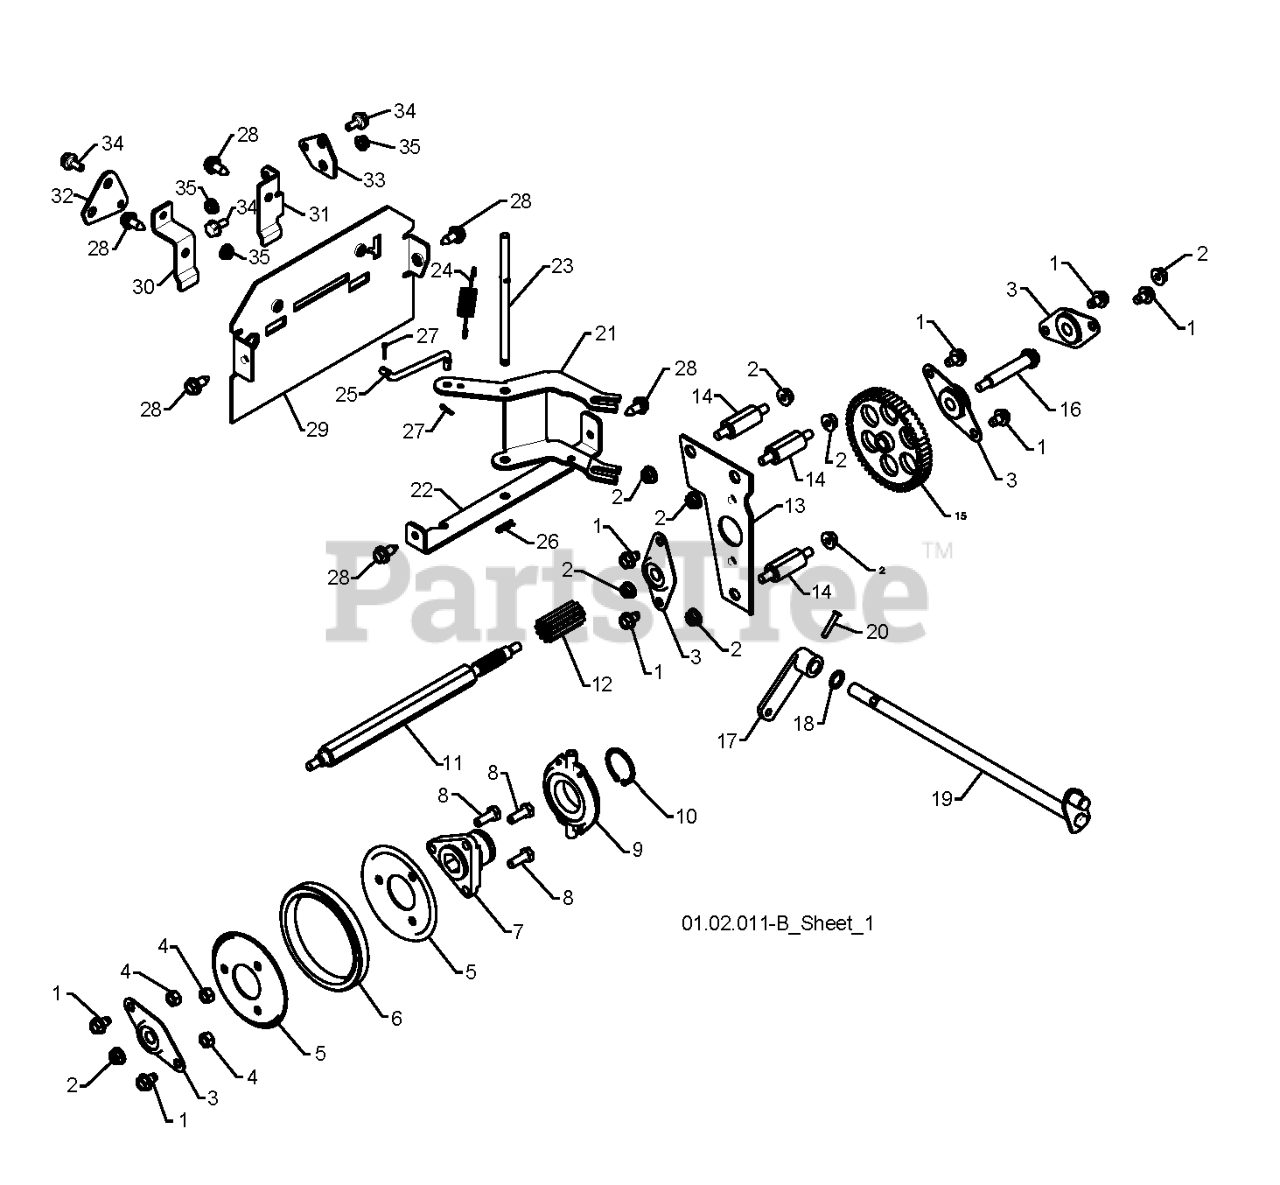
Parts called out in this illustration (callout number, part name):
1	Screw 5/16-18 x 1/2 Hex, Self Tapping 5/16-18 x 1/2
2	NUT.LOCK.5/16-18
3	BEARING, FLANGE
4	NUT.CENTERLOCK.5/16-
5	PLATE.RUBBER.WHEEL
6	RING, RUBBER WHEEL
7	HUB, RUBBER WHEEL
8	BOLT
9	TRUNNION BEARING ASSY
10	RETAINING RING (2 2)(3 2)
11	SHAFT.HEX.LONG
12	GEAR, PINION
13	AUXILLARY PLATE
14	SPACER, PLATE
15	GEAR, INTERMEDIATE
16	SHAFT, AUXILIARY
17	ARM, AUGER CONTROL
18	THRUST WASHER
19	CONTROL.SHAFT.ASM
20	CLEVIS PIN
21	LEVER, SPEED CONTROL
22	BRACKET, PIVOT, SHIFT
23	PIN, PIVOT
24	SPRING, BIAS
25	LINK, SPEED CONTROL
26	RETAINER CLIP PM
27	RETAINER CLIP
28	BOLT.HEX.HD.WASHER.5/16-18X.75
29	PLATE.REAR.SNOW.PNT.ORANGE
30	BRACKET.SHIFTER.PLATE.BZP
31	BRACKET.CLUTCH.PLATE.BZP
32	PLATE.SHIFTER.BZP
33	PLATE.CLUTCH.BZP
34	BOLT.SHOULDER.3/X.25
35	NUT.HEX.FLANGE.1/4
